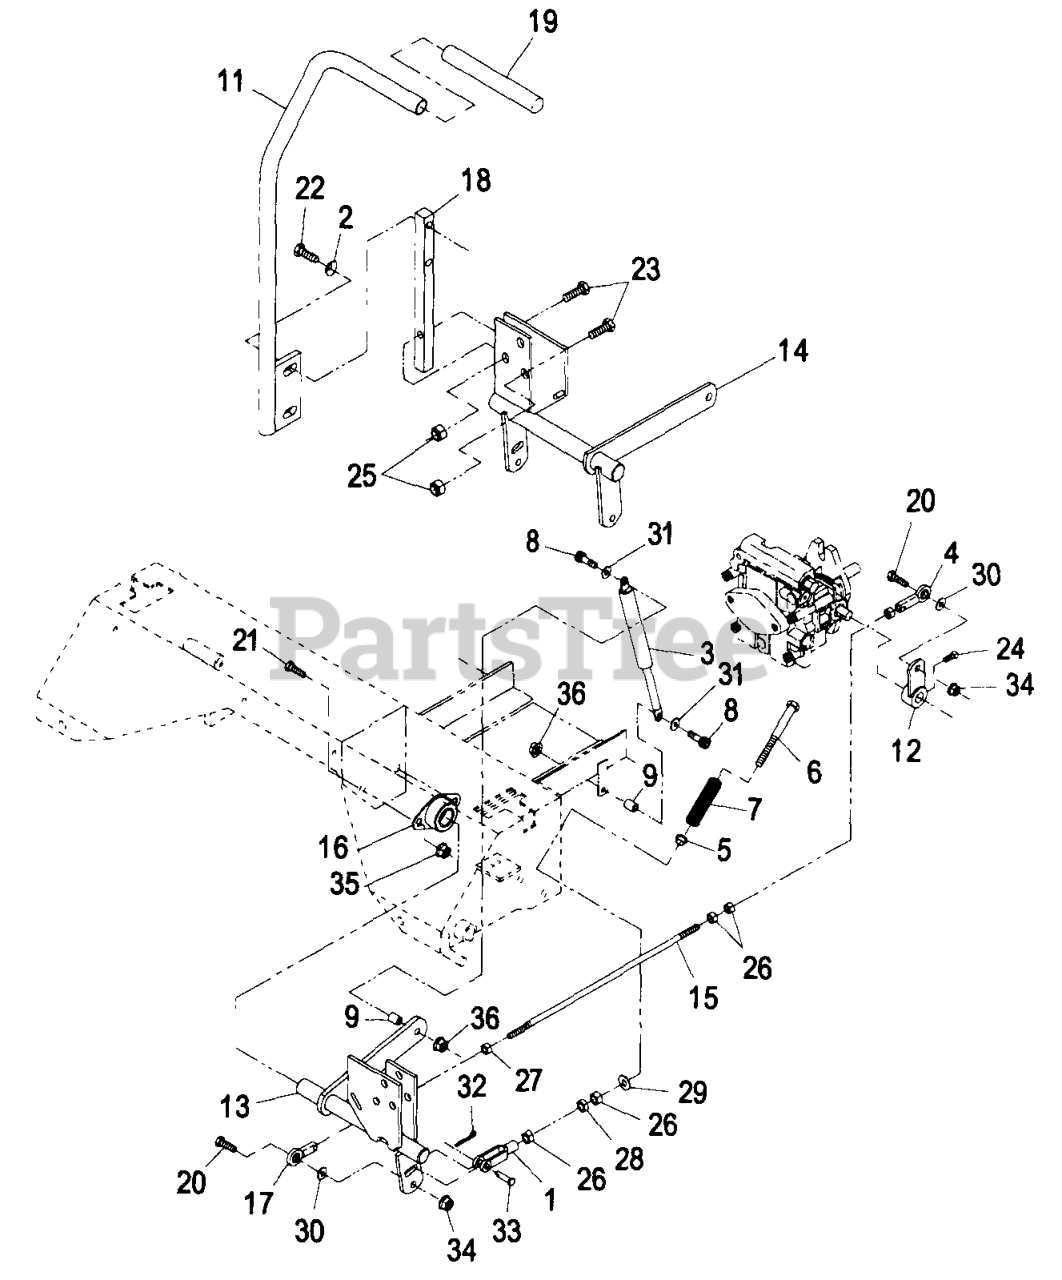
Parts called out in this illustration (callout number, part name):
1	YOKE-ADJUSTABLE
4	BALLJOINT-RH
5	BUSHING-FLANGED
6	BOLT-RETURN, NEUTRAL
7	SPRING-RETURN, NEUTRAL
8	SCREW-HSH
11	ASM,LEVER/GRIP RH
16	BEARING-FLANGE, SIDE
17	BALLJOINT-LH
18	ARM-CONTROL, SHAFT
19	GRIP-CONTROL, MOTION
24	SCREW-SET
33	PIN-CLEVIS
